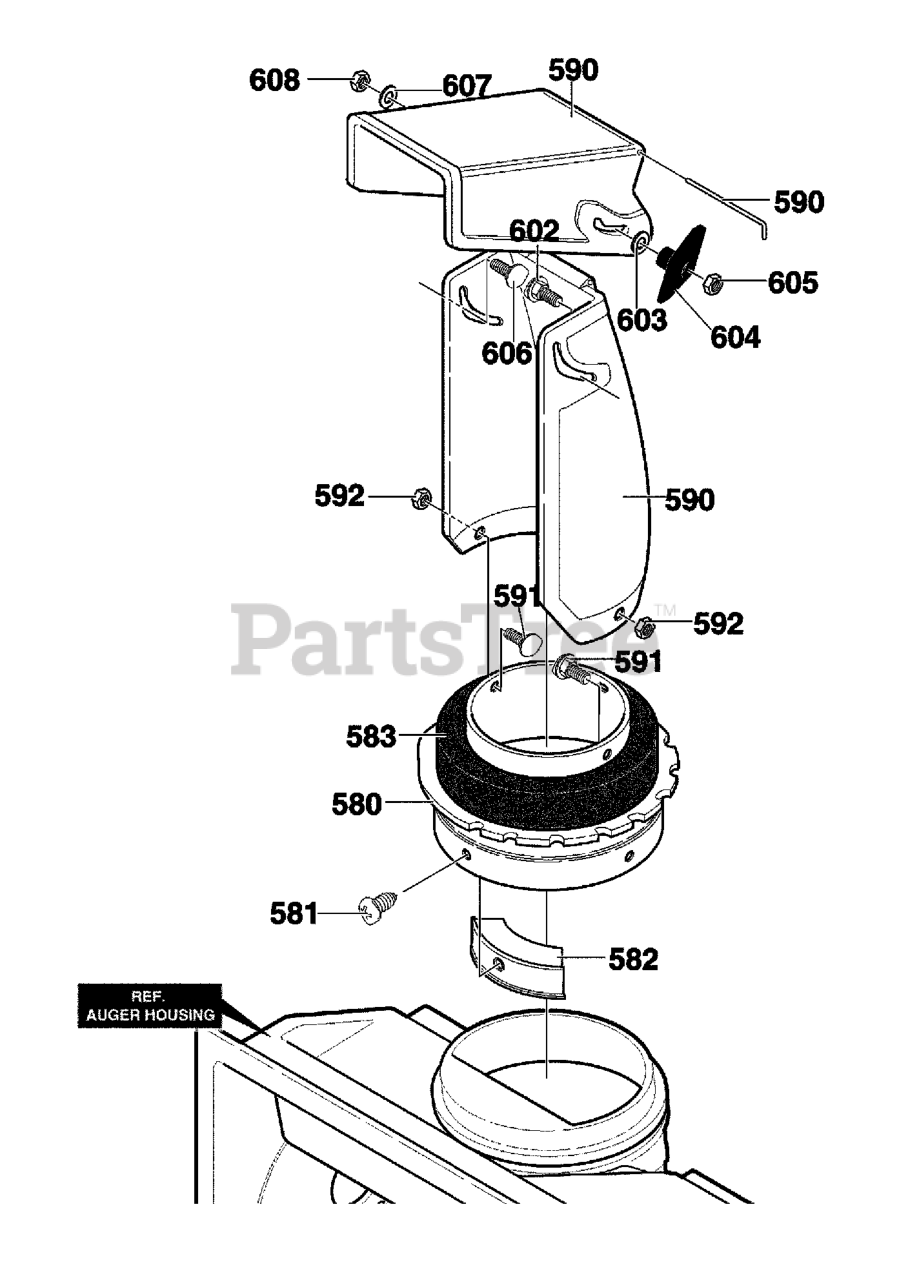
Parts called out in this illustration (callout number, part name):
580	RING, CHUTE
581	SCREW, #10X.50
582	GUIDE, CHUTE
583	DONUT FOAM
590	CHUTE ASSY.
591	SCREW 1/4-20X.50
592	NUT, CNTRLK 1/4-20
602	BOLT, 5/16-18X1.25 CARR.
603	WASHER, FLAT .349X.69X.066
604	KNOB, T
605	NUT, 5/16-18 REGHEX
606	SCREW, 5/16-18 x 0.75
607	WASHER, FLAT .349X.69X.066
608	NUT, 5/16-18 REGHEXCTRLK
